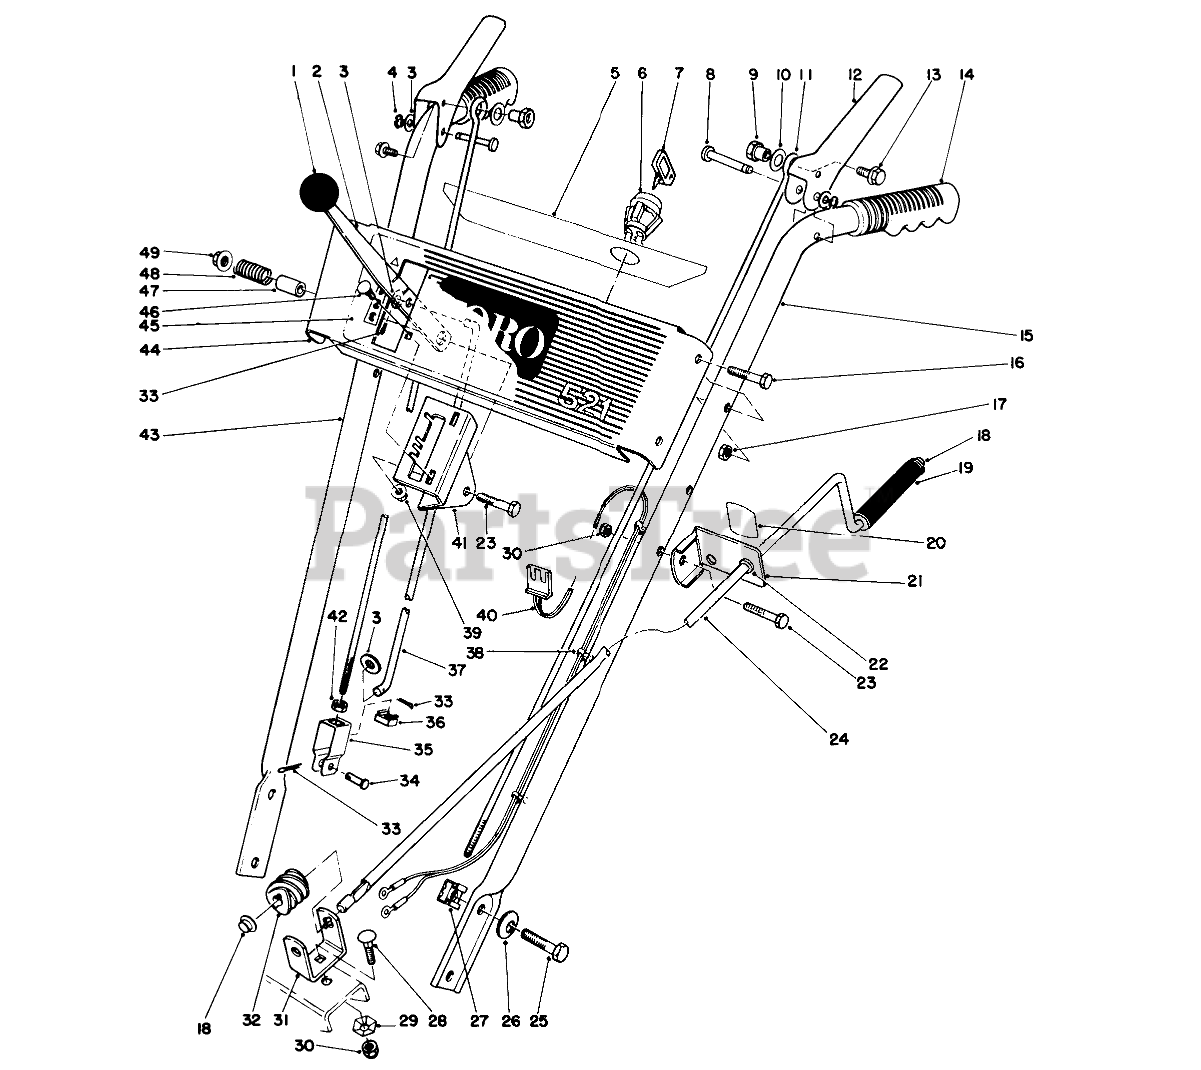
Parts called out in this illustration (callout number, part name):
2	SPEED SELECTOR B
3	WASHER-PLAIN
4	RING-CLIP
5	DECAL - ESCUTCHEON BACK
6	SWITCH
7	KEY-IGNITION
8	PIN-LEVER, CONTROL
9	POST-MOUNTING, LINKAGE
10	WASHER-FLAT
11	LINK-UPPER
12	HANDLE-CONTROL
13	SCREW-HHF
14	GRIP-HANDLE
15	Handle-Left
16	SCREW-HH
17	NUT-LOCK, NI
18	RETAINER-PUSH ON
19	Grip-Rod
20	DECAL-CHUTE DIRECTION
21	Bracket-Chute Control (Incl. Ref. #20 & 22)
22	Bushing
23	SCREW-HH
24	ROD-CONTROL, CHUTE
25	SCREW-HH
26	WASHER-BELLEVILLE
28	SCREW-CARR
29	WASHER-LOCK
30	NUT-LOCK, NI
31	BRACKET-WORM
32	GEAR-WORM, CHUTE
33	PIN-COTTER
34	PIN-CLEVIS
35	CLEVIS
36	NUT-RETAINED
37	ROD-SELECTOR, SPEED
38	Mount-Wire
39	NUT-HF
40	Wire Harness Assembly (Incl. Ref. #38)
41	Mount-Speed Selector
42	NUT-JAM
43	Handle-Right
44	ESCUTCHEON PLT B
45	DECAL ESCUTCHEON
46	SCREW-CARR
47	SPACER
48	SPRING
49	NUT-HF
50	WASHER-FLAT
